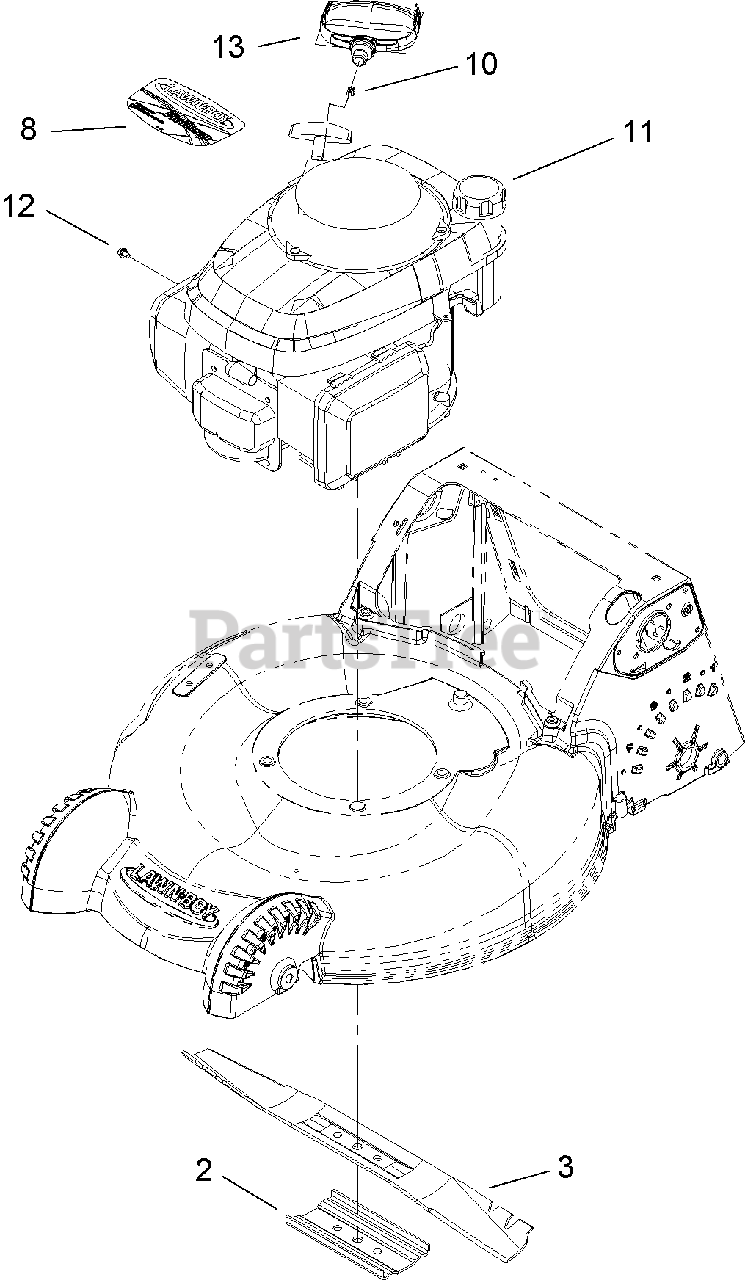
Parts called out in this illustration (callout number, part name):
2	SUPPORT-BLADE
3	BLADE-21 INCH
8	DECAL-ENGINE
10	STOP-ROPE
12	SCREW-HWH
13	HANDLE-RECOIL
